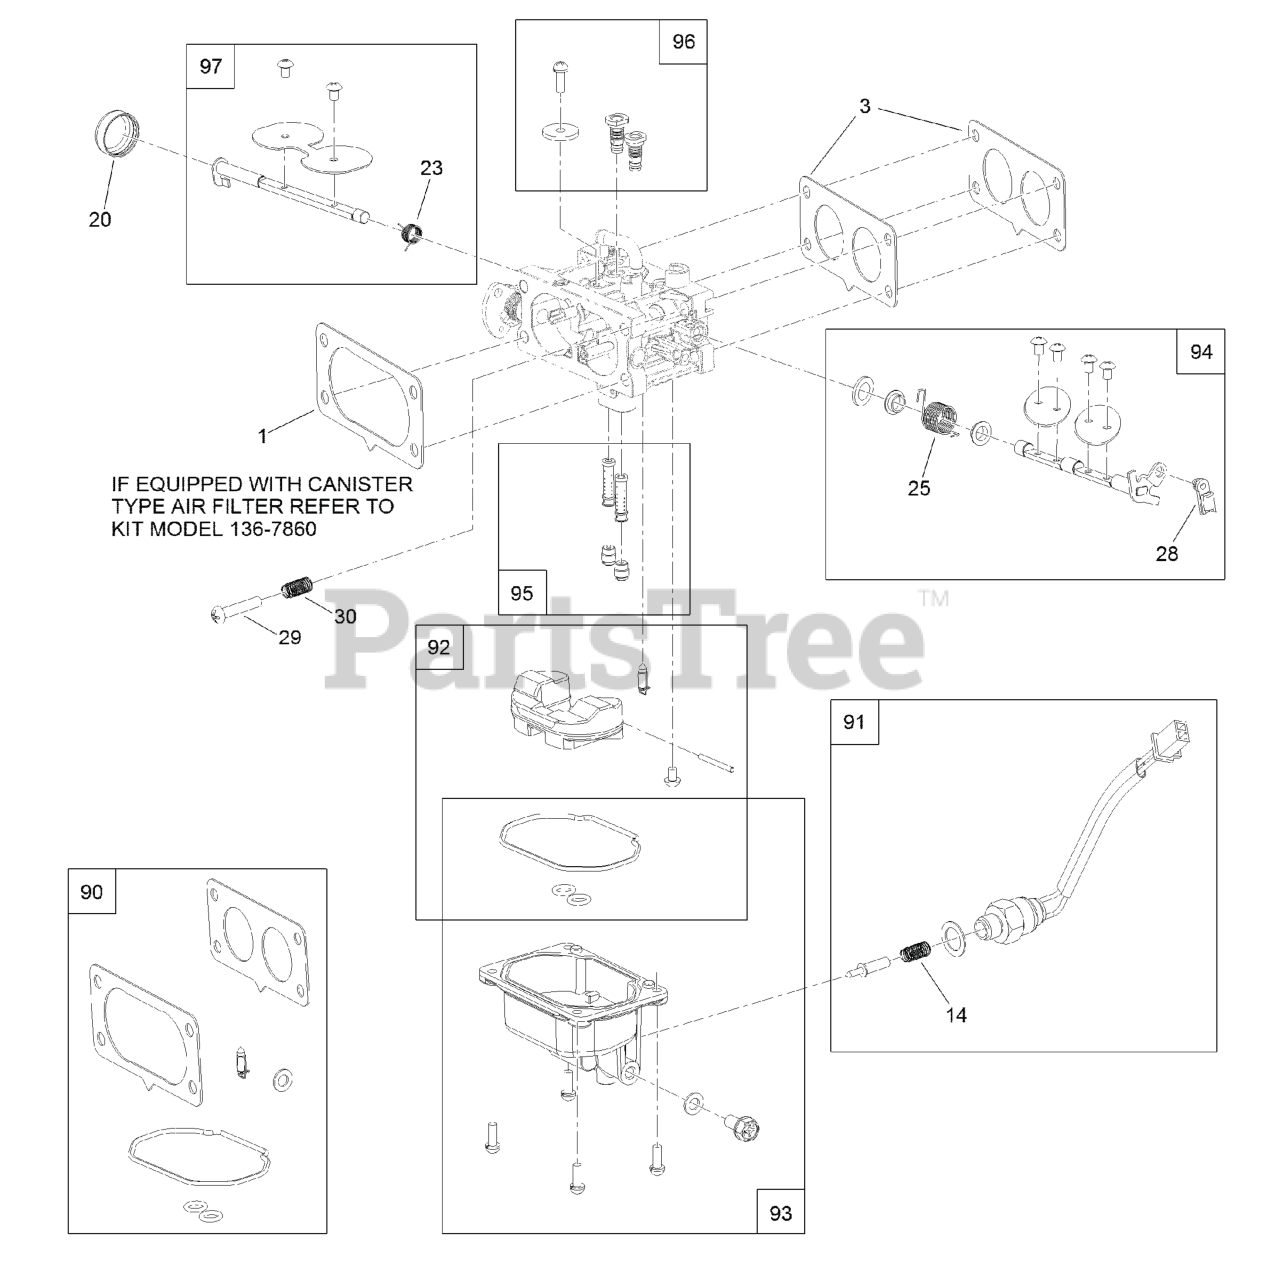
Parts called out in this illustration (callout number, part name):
1	GASKET-CARBURETOR
3	GASKET-CARBURETOR
20	COVER-SHAFT, CHOKE
28	CLAMP-LOCK
29	SCREW-PPH
90	CARBURETOR REPAIR KIT
91	SOLENOID KIT
92	FLOAT KIT
93	BOWL KIT
94	THROTTLE SHAFT KIT
95	NOZZLE AND JET KIT
96	Air Jet Kit
97	CHOKE SHAFT KIT
